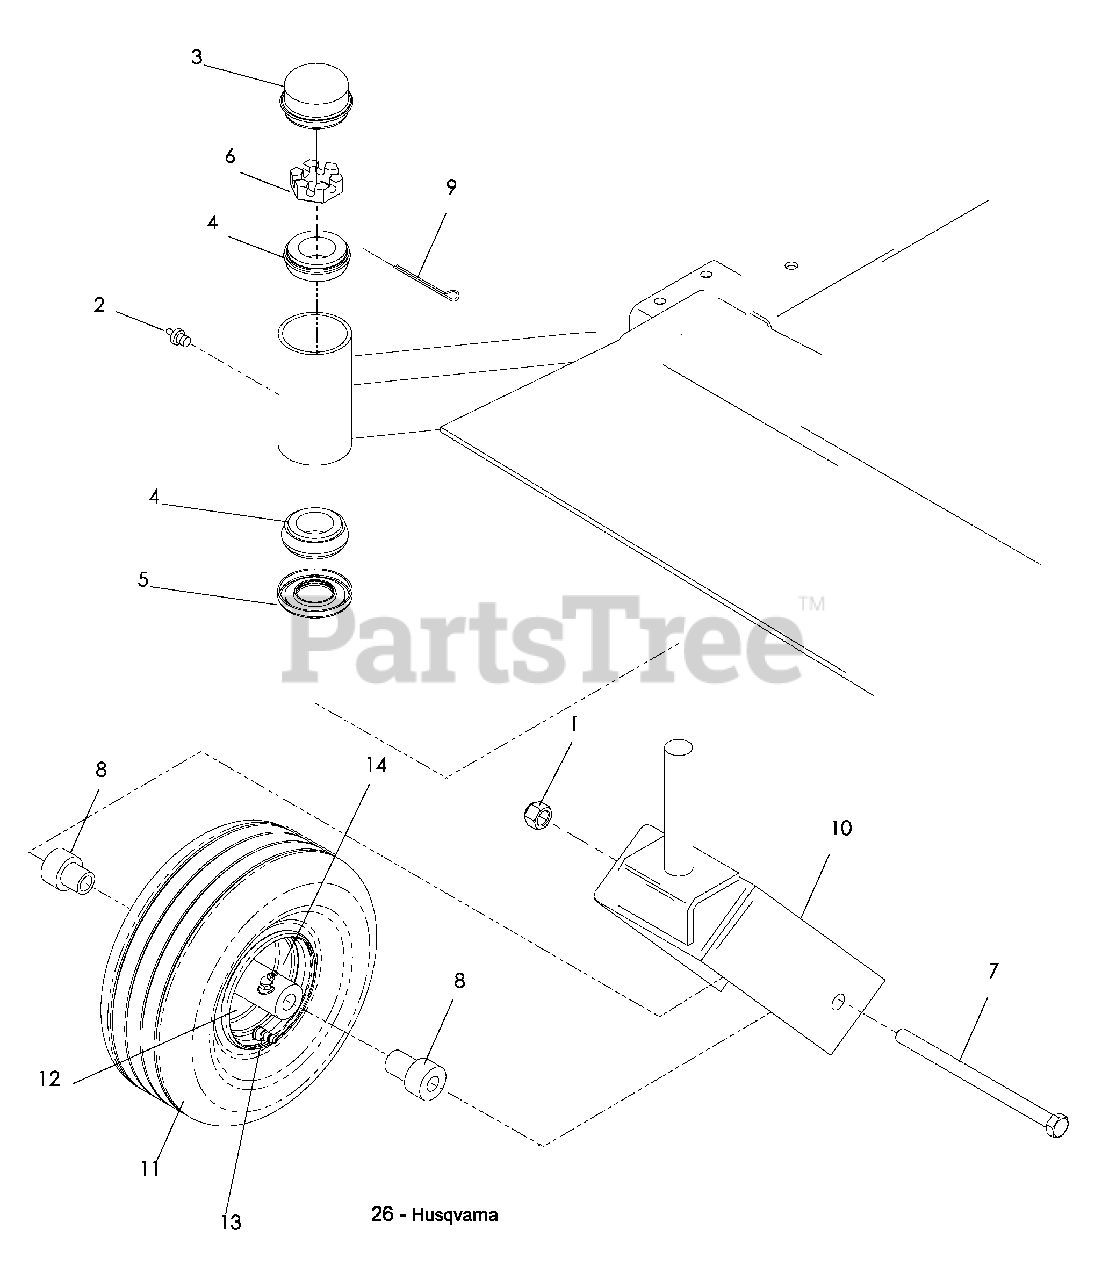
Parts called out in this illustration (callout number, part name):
1	NUT ½-13 HEX NYLOC
3	CAP, GREASE
4	BEARING, TAPERED
6	NUT 1-14, SLOTTED JAM
7	HCS ½-13 x 9½
9	PIN, COTTER 1/8 x
10	CASTER YOKE
11	TIRE, COMPLETE
13	VALVE STEM
14	ZERK
